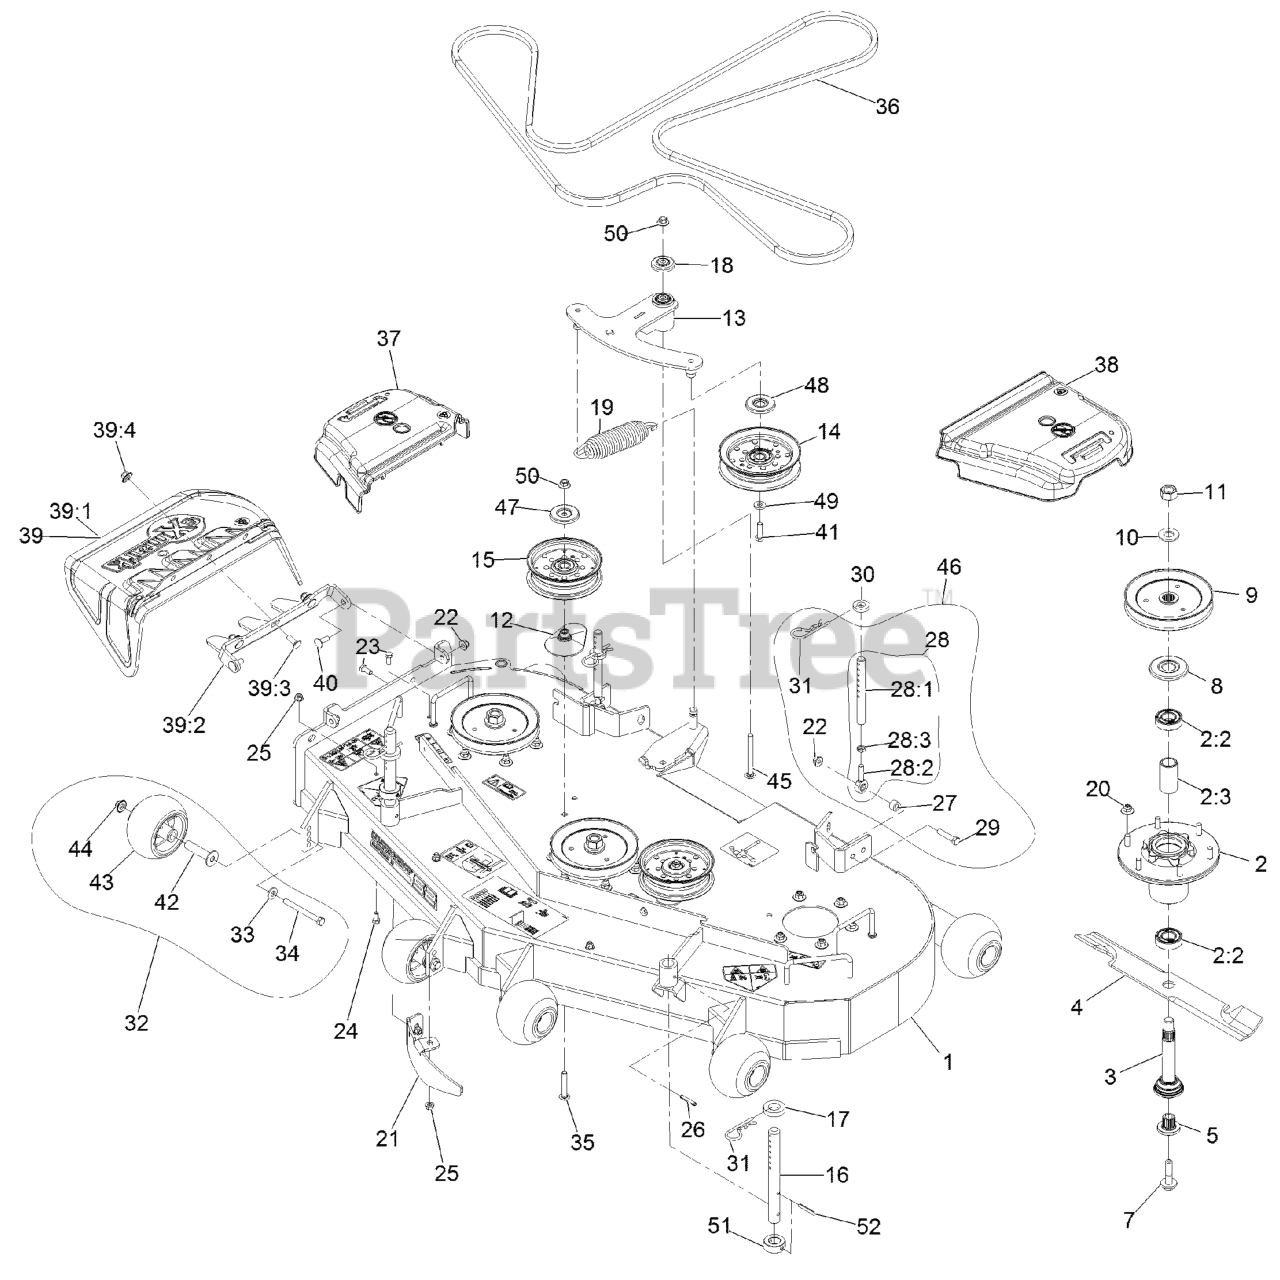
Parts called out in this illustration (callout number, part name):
1	ASM, DECK W/ DECALS, 52"
2	ASM-CUTTER HSG WITH BEARINGS
2:2	BEARING-BALL
2:3	SPACER-BEARING
3	ASM-SPINDLE AND SEAL
5	BUSHING,SPLINED
7	SCREW,SEMS 1/2-20 X 2.19
8	GUARD,BEARING TOP .989
9	SHEAVE,BLADE DRIVE 6.50
11	NUT-HEX
12	SPACER-PULLEY
13	ASM, DECK IDLER
14	IDLER-PULLEY, FLAT
15	IDLER-PULLEY, FLAT 5.00X1
16	Rod, Deck Support
17	SPACER-DECK SUPPORT
18	GUARD-TOP
19	SPRING-EXTENSION
20	Nut-Nyloc 3/8-16 Flg
21	BAFFLE, DOGLEG
22	NUT-HF, NI
23	SCREW-HH
24	SCREW-HH
25	NUT-HF, NI
28:1	LINK,SUPPORT
28:2	BALLJOINT
28:3	NUT-HJ
29	SCREW-HH
31	PIN,HAIR COTTER
32	KIT, ANTI-SCALP ROLLER
33	WASHER-BELLEVILLE
34	SCREW-HH 3/8-16 X 3 3/4 GR 8
35	BOLT-CARR, SHORT NECK
36	BELT, DECK
37	COVER-BELT, RH
38	COVER-BELT, LH
39	ASM, DISCHARGE CHUTE
39:1	CHUTE,DISCHARGE
39:2	BRACKET, DISCHARGE CHUTE
39:3	SCREW-CARR
39:4	Nut-Nyloc 3/8-16 Flg
40	SCREW-CARR
41	SCREW-HH
42	AXLE, ROLLER
43	ROLLER-SCALP, ANTI
44	Nut-Nyloc 3/8-16 Flg
45	SCREW-CARR
46	KIT,SUPPORT LINK W/PIN
47	SHIELD-DUST
48	SHIELD-GUARD, DUST
51	Collar, Deck Height Pin
52	PIN-ROLL
